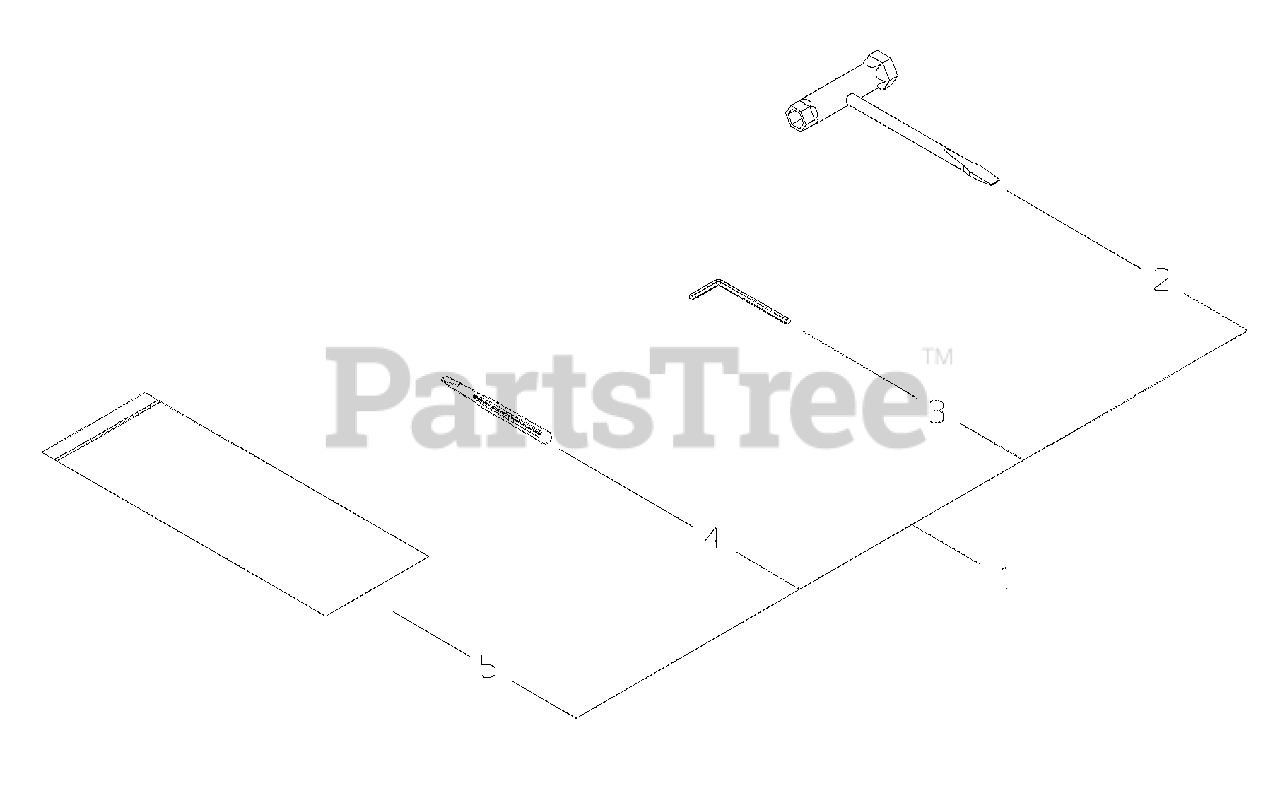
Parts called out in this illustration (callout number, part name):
1	TOOL KIT, SERVICE
2	T-WRENCH 13×19 MM
3	WRENCH, ALLEN 4 MM
4	SCREWDRIVER, PLASTIC
5	BAG, TOOL
